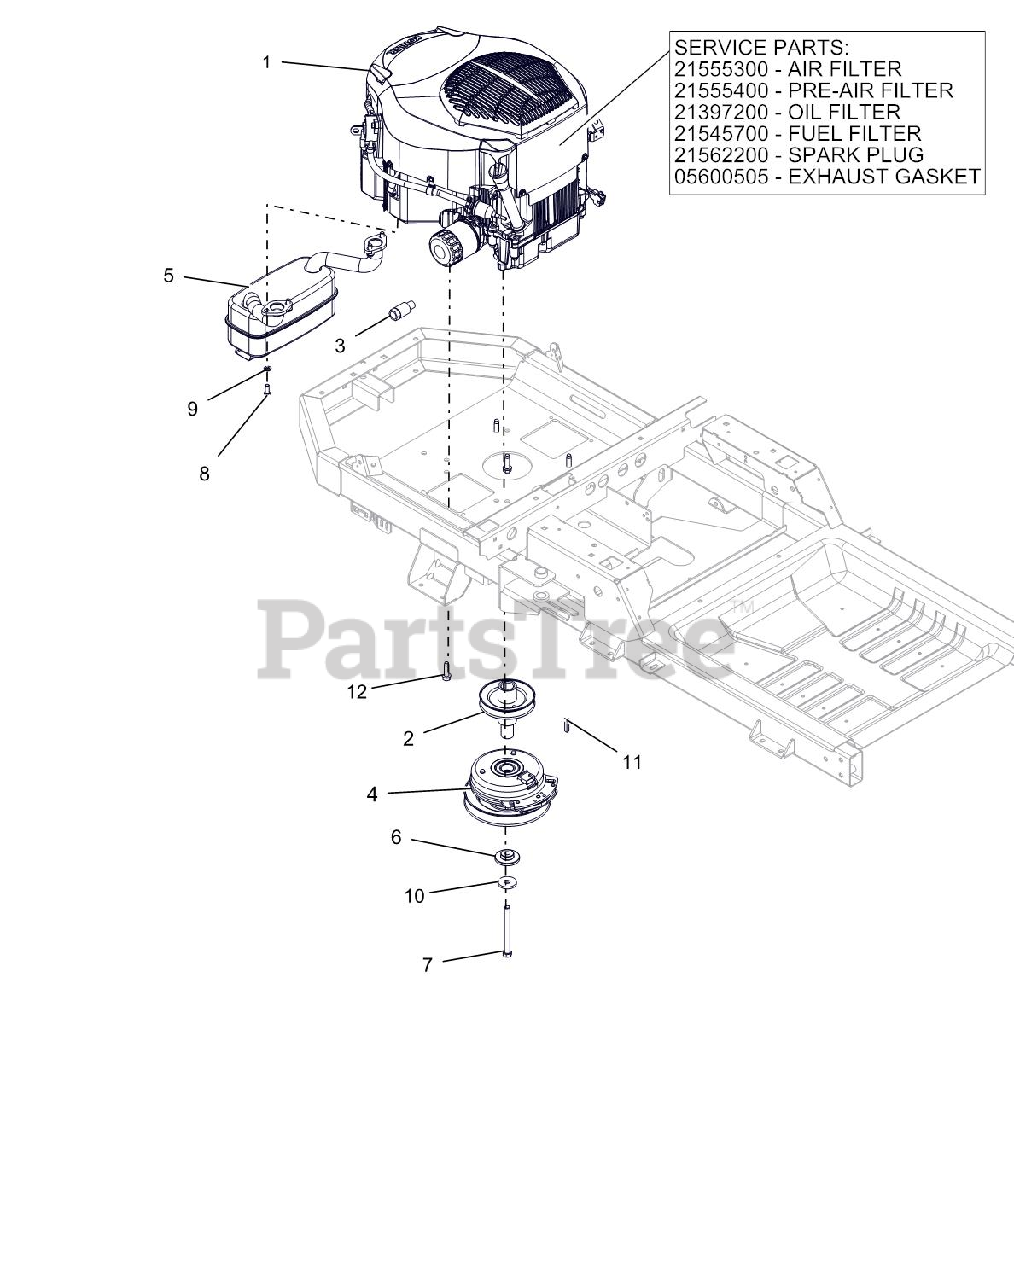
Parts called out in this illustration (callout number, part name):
1	FILTER, OIL - KOH CV20
1	GASKET, MUFFLER COURAGE TWIN
1	FILTER-FUEL KOHLER COURAGE PRO
1	AIR FILTER, KOHLER
1	PRE CLEANER, KOHLER
1	PLUG, SPARK (RFI)
1	ENGINE-KOHLER PRO 24HP W/SC
2	WLDMT, DRIVE SHEAVE-X YWZC
3	DRAIN, OIL
4	CLUTCH,105FTLB MONOPOLE 6.83"
5	MUFFLER - KOHLER
6	BSHG-FLG .469X1.06X.574X2.0
7	BLT-HEX.438-20X4.5GR8YZ NYTORQ
8	SCR-CAP .31-18X.75 S/HD
9	WSHR-LK .31X.078 REG YWZC
10	WASHER, 7/16" SPRING DISK
11	KEY-SQ .25 X 1.25 X .25 SAE
12	SCR-TAP .38-16X1.25 HWH TR YZ
